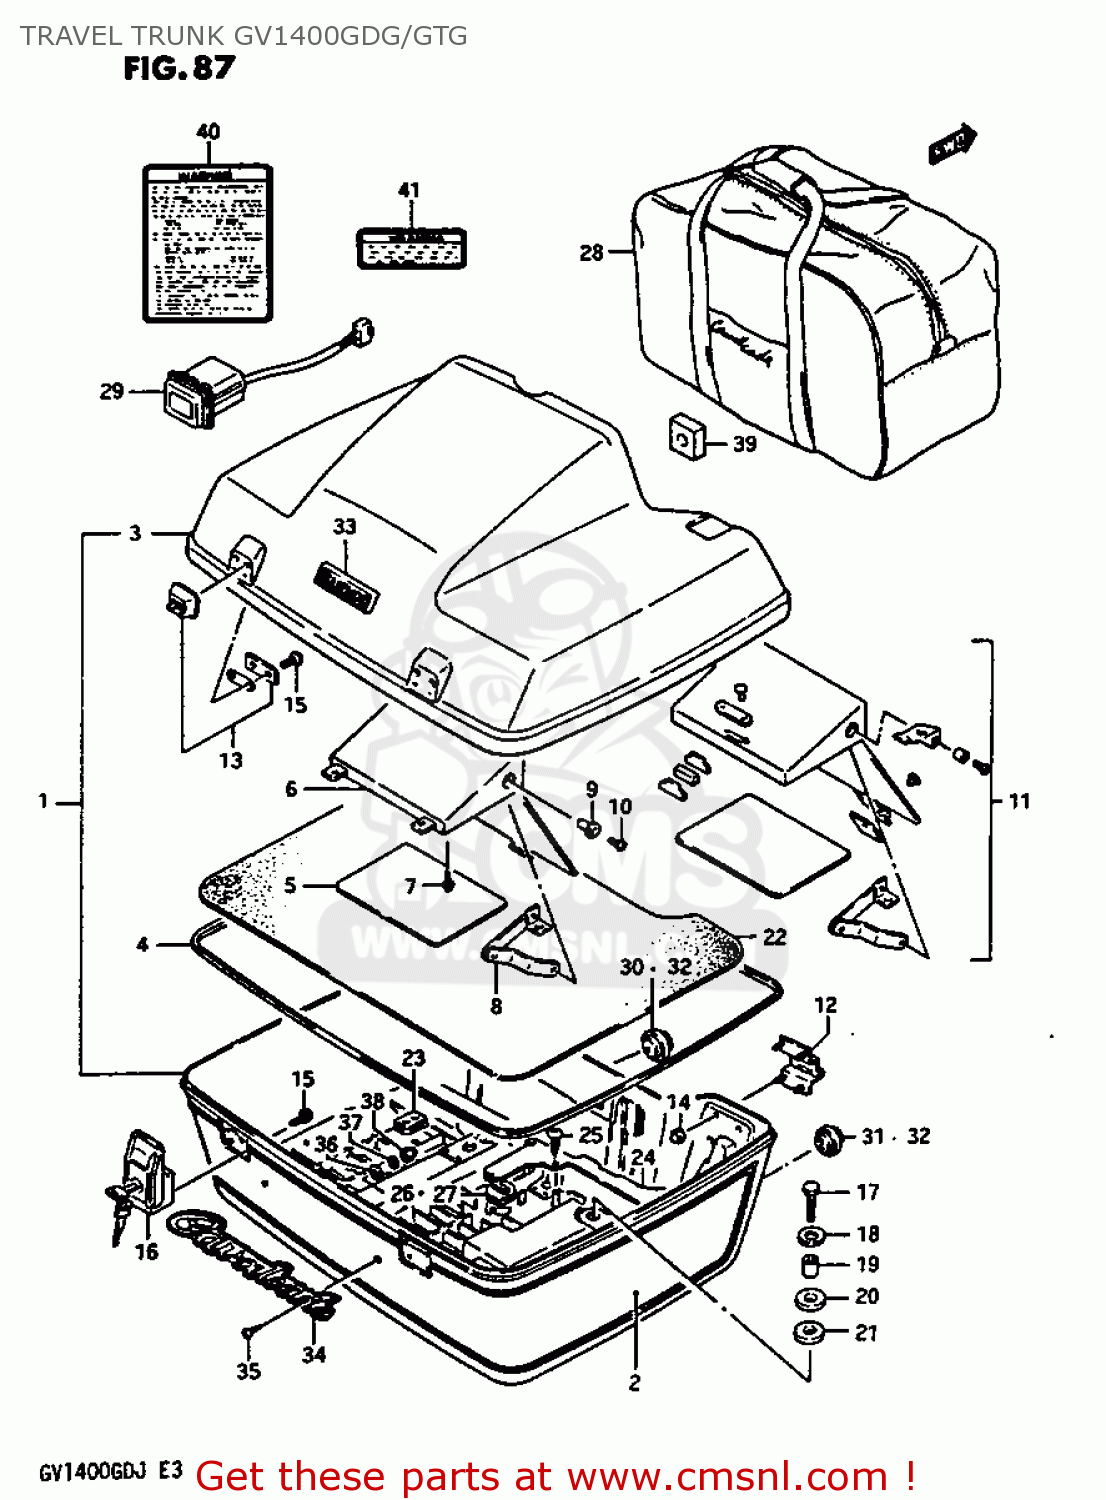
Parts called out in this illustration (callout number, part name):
1	TRUNK ASSEMBLY,TRAVEL
2	TAPE SET,TRAVEL TRUNK
3	LID,TRAVEL TRUNK
4	SEAL,TRAVEL TRUNK LID
5	MIRROR
6	BASE, MIRROR
7	SCREW
8	STOPPER,MIRROR OPEN
9	WASHER
10	SCREW, 4X10
12	HINGE,TRAVEL TRUNK
13	PLATE,TRUNK LID LOCK
14	NUT
15	SCREW
16	LOCK SET,SIDE BAG
17	BOLT
18	WASHER (6.5X29X1.6)
19	SPACER(6.3X9.3X16.5)
20	CUSHION
21	CUSHION
22	SEAT,TRAVEL TRUNK BODY
23	GROMMET
24	COVER, AIR HOSE
25	SCREW
26	GROMMET
27	GROMMET
28	LUGGAGE BAG,TRAVEL TRUNK
29	SWITCH ASSEMBLY,AIR AUXILIARY
30	GROMMET
31	GROMMET
32	GROMMET,HOSE AIRSEAT
33	EMBLEM,TRAVEL TRUNK,UPPER
34	EMBLEM,TRAVEL TRUNK,LOWER
35	SCREW
36	WASHER
37	WASHER
38	NUT
39	SEAL
40	LABEL (WARNING)
41	LABEL, WARNING
